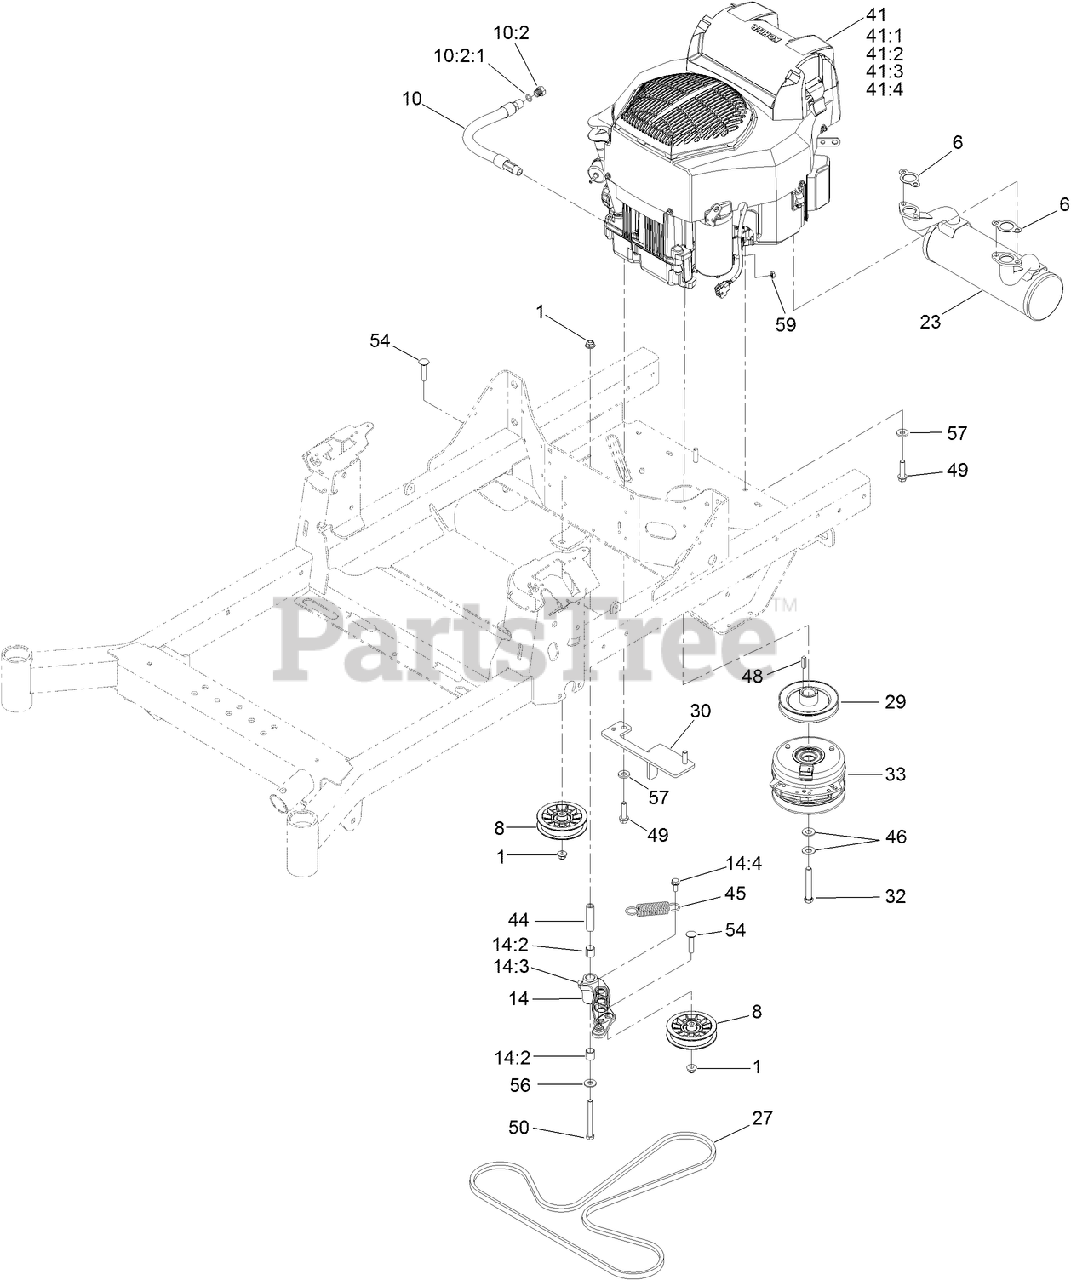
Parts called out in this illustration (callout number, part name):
1	NUT-HF, NI
8	PULLEY-FLAT IDLER
10	OIL DRAIN HOSE ASM
10:2	PLUG-HH
10:2:1	O-RING
14	IDLER ARM ASM
14:2	SLEEVE-BEARING
14:3	FITTING-GREASE, 90 DEG
14:4	SCREW-THD ROLL, HWH
23	MUFFLER-KOHLER AES
27	BELT-V
29	SHEAVE-ENGINE
30	ANCHOR-CLUTCH
32	SCREW-HH W/LOCTITE
33	CLUTCH-PTO
41:1	KOHLER 16 083 01-S ENGINE AIR FILTER
41:2	KOHLER 25 050 44-S ENGINE OIL FILTER
41:3	KOHLER 24 050 13-S FUEL FILTER
41:4	KOHLER 25 083 04-S SAFETY FILTER
44	BUSHING-PIVOT, IDLER
45	SPRING-EXTENSION
46	WASHER-SPRING
49	SCREW-HWH
50	SCREW-HH
54	SCREW-CARR
56	WASHER-FLAT
57	WASHER-BELLEVILLE
59	NUT-HF
